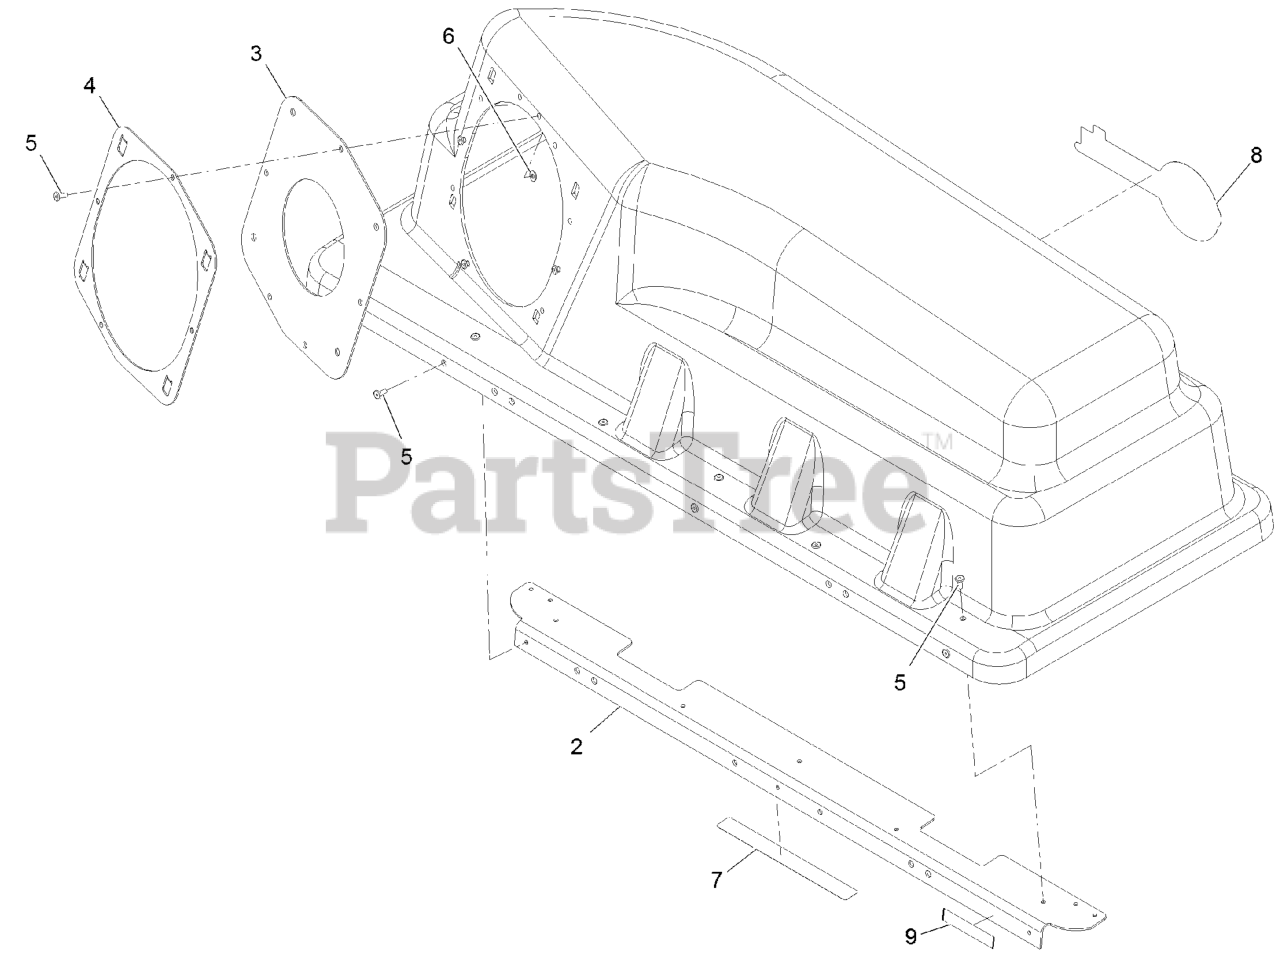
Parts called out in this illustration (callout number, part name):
2	STIFFENER-BAGGER, TOP
4	RING-RETAINER
5	RIVET-BLIND
6	WASHER-FLAT
7	DECAL-CRUSH HAZARD BAGGER
8	DECAL-EXMARK LOGO
9	DECAL-WARNING
